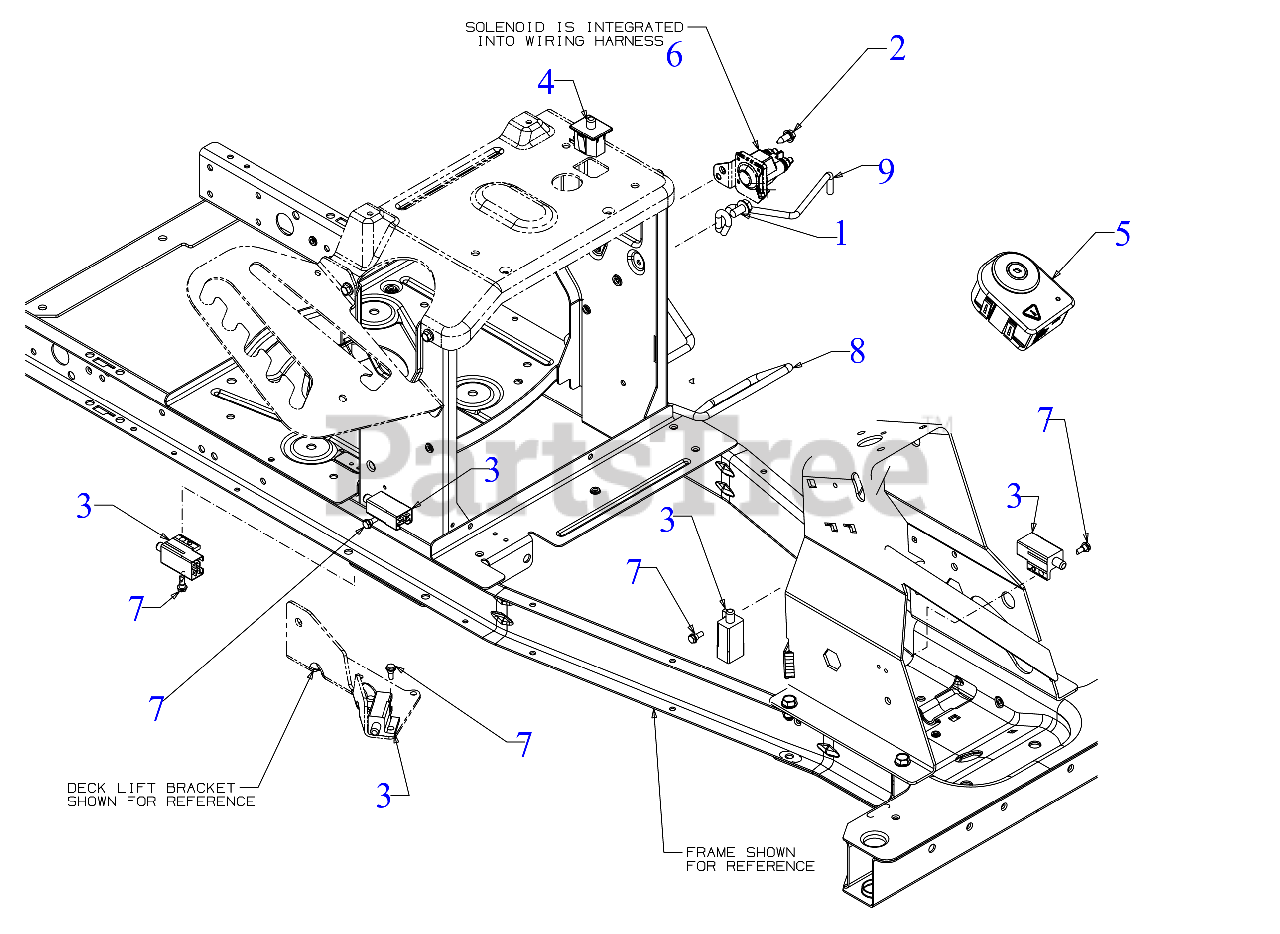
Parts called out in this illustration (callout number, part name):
1	SCREW 5/16-18 x .750
2	SCREW 1/4-20X.625
3	INTERLOCK SWITCH (NO/NC)
4	SEAT SWITCH N/C,N/C
5	IGNITION MODULE SWITCH RMC (MAN PTO BLK)
6	HARNESS (HYD/SOL/RMC)
7	SHOULDER SCREW
8	BATTERY TRAY ROD
9	BATTERY HOLD DOWN ROD
